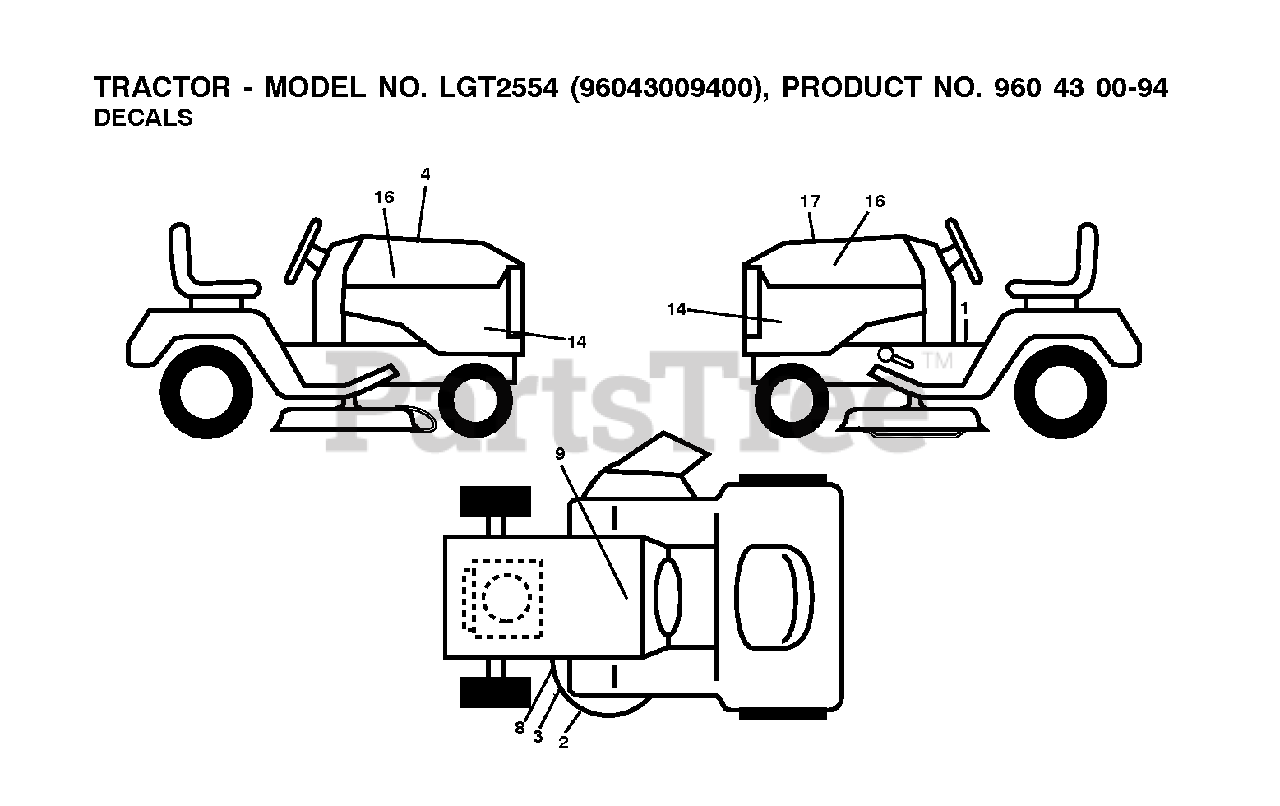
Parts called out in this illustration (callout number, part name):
1	DECAL.FENDER.WARNING.ENG
2	DECAL.ENG.BS.26 HP.PR
3	DECAL.WARN.KEEP.HAND.AWAY
4	DECAL.WARNING.CUST.RESP.E85.
6	DECAL.ENG.BS.26 HP.PR
8	DECAL.MOWER
9	DECAL BTRY SYMBOLS
16	RP.DECAL.BADGE.170MM.TEXTLOGO
